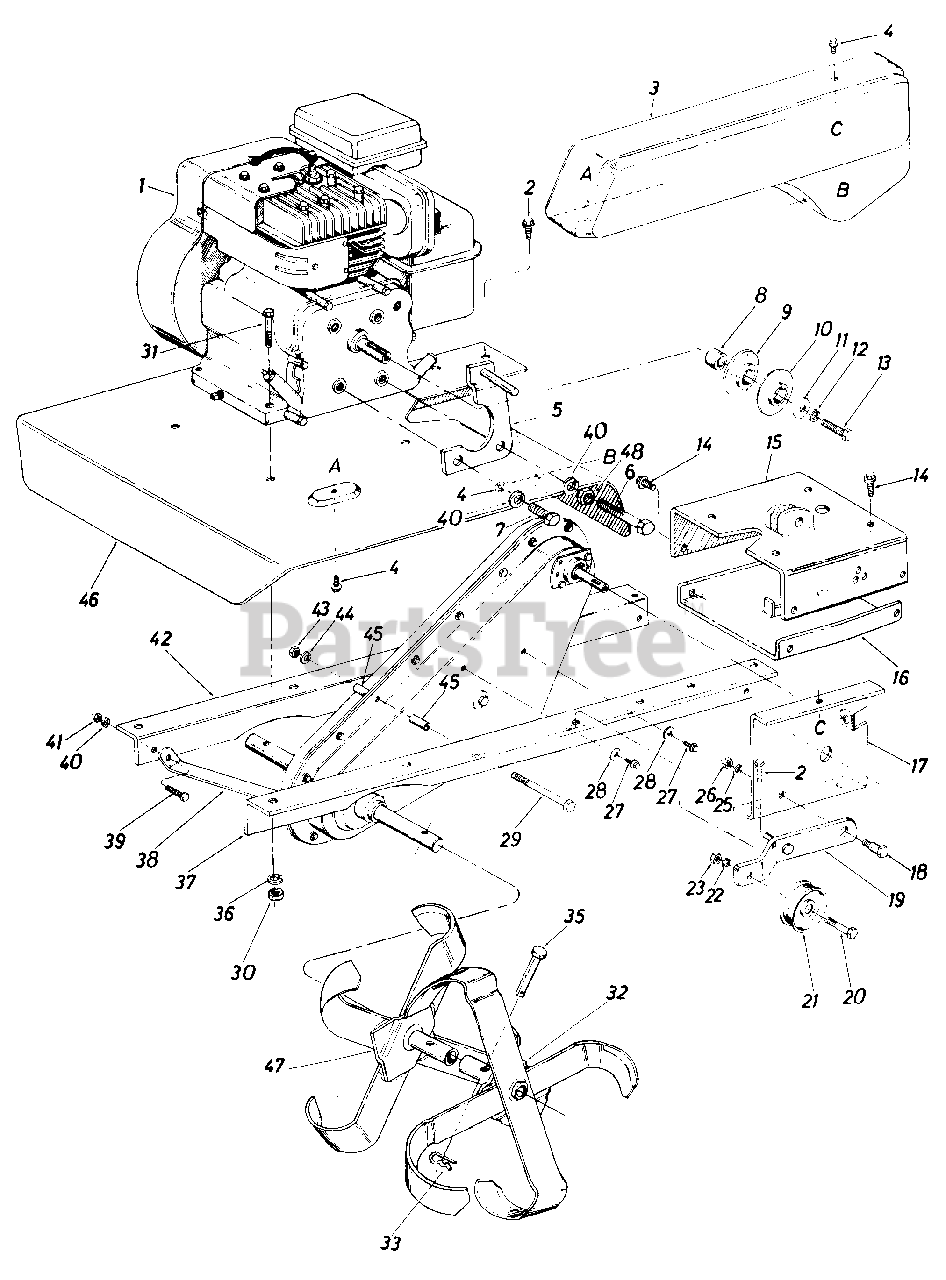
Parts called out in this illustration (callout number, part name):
1	Engine
2	Hex Wash. Hd. Self-Tap Scr. 5/16-24 x .50" Lg.
3	Belt Cover
4	Hex Wash. Hd. Self-Tap Scr. 1/4 -20 x .50" Lg.
5	Belt Keeper Brkt. Ass'y.
6	Hex Bolt 5/16-24 x 2.25 Lg. (Grade 5)
7	Hex Bolt 5/16-24 x .62" Lg. (Grade 5)
8	Spacer
9	Pulley Half
10	Pulley Half
11	Fl-Wash. 3/8" I.D. x 1.25" O.D. x .100
12	L-Wash. 3/8" I.D.
13	Hex Scr. 3/8-24 x 1.00" Lg.
14	Hex Wash. Hd. Self-Tap Scr. 3/8-16 x .75" Lg.
15	Handle Mounting Brkt. Ass'y.
16	U-Channel Brkt. Ass'y.
17	Idler Mounting Brkt.
18	Shld. Bolt
19	Idler Brkt. Ass'y.
20	Hex Scr. 3/8-16 x 1.50" Lg.
21	Idler Pulley
22	L-Wash. 3/8" I.D.*
23	Hex Nut 3/8-16 Thd.
25	L-Wash. 3/8" I.D.*
26	Hex Nut 3/8-16 Thd.
27	Hex Wash. Hd. Self-Tap Scr. 1/4-20 x .50" Lg.
28	Belleville Washer. .26 I.D. x .75 O.D. x .060
29	Hex Scr. 5/16-18 x 3.0" Lg.
30	Hex Nut 5/16-18 Thd.*
31	Hex Bolt 5/16-18 x 1.50" Lg.
32	See Tine Chart
35	Clevis Pin
36	L-Wash. 5/16" I.D.*
37	Frame Rail-L.H.
38	Front Brace Brkt.
39	Hex Scr. 5/16-18 x .75" Lg.*
40	L-Wash. 5/16" I.D.*
41	Hex Cent. L-Nut 5/16-18 Thd.
42	Frame Rail-R.H.
43	Hex Cent. L-Nut 5/16-18 Thd.
44	L-Wash. 5/16" I.D.*
45	Spacer
46	Tine Shield
47	See Tine Chart
48	Hex Nut 5/16-24 Thd.*
